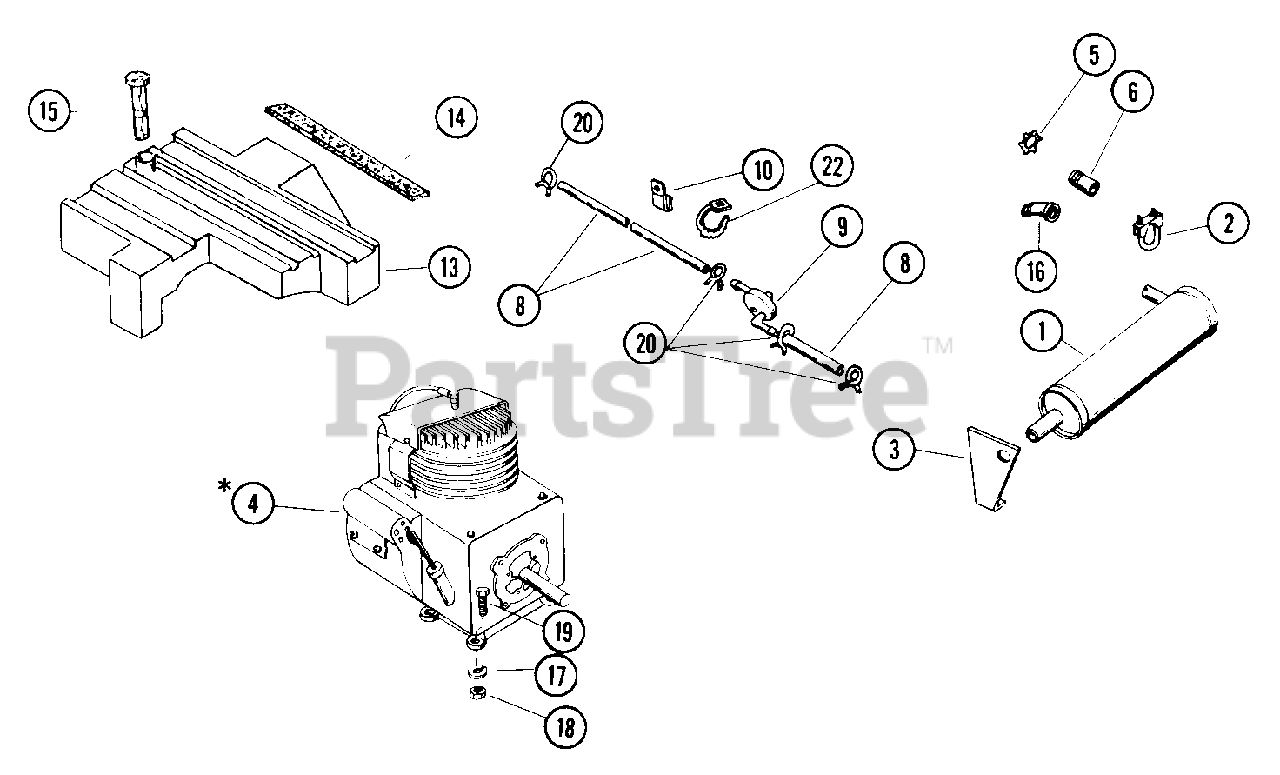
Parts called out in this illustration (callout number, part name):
1	MUFFLER
2	EXHAUST CLAMP - 1 1/2
2	EXHAUST CLAMP - 1 3/4
3	MUFFLER BRACKET
5	NUT-LK CONDUIT 1.00
5	NUT-LK CONDUIT 1.25
6	ADAPTER
6	PIPE
8	HOSE (SERV. ONLY)
9	FUEL FILTER
10	J-CLAMP
13	GAS TANK
14	1/4 X 3/4 X 1 IN FOAM TAPE
15	GAS GAUGE & CAP
16	STREET ELBOW 1-1/4 X 45 DEGREE
16	45 DEG ELBOW
17	WSHR-LK .375X.094 MED PL
18	NUT-HEX .375-16
19	BLT-HEX .38-16X1.50 PL GR5
20	CLAMP-HOSE WIR.490/.510X.092#8
22	TIE DOWN
